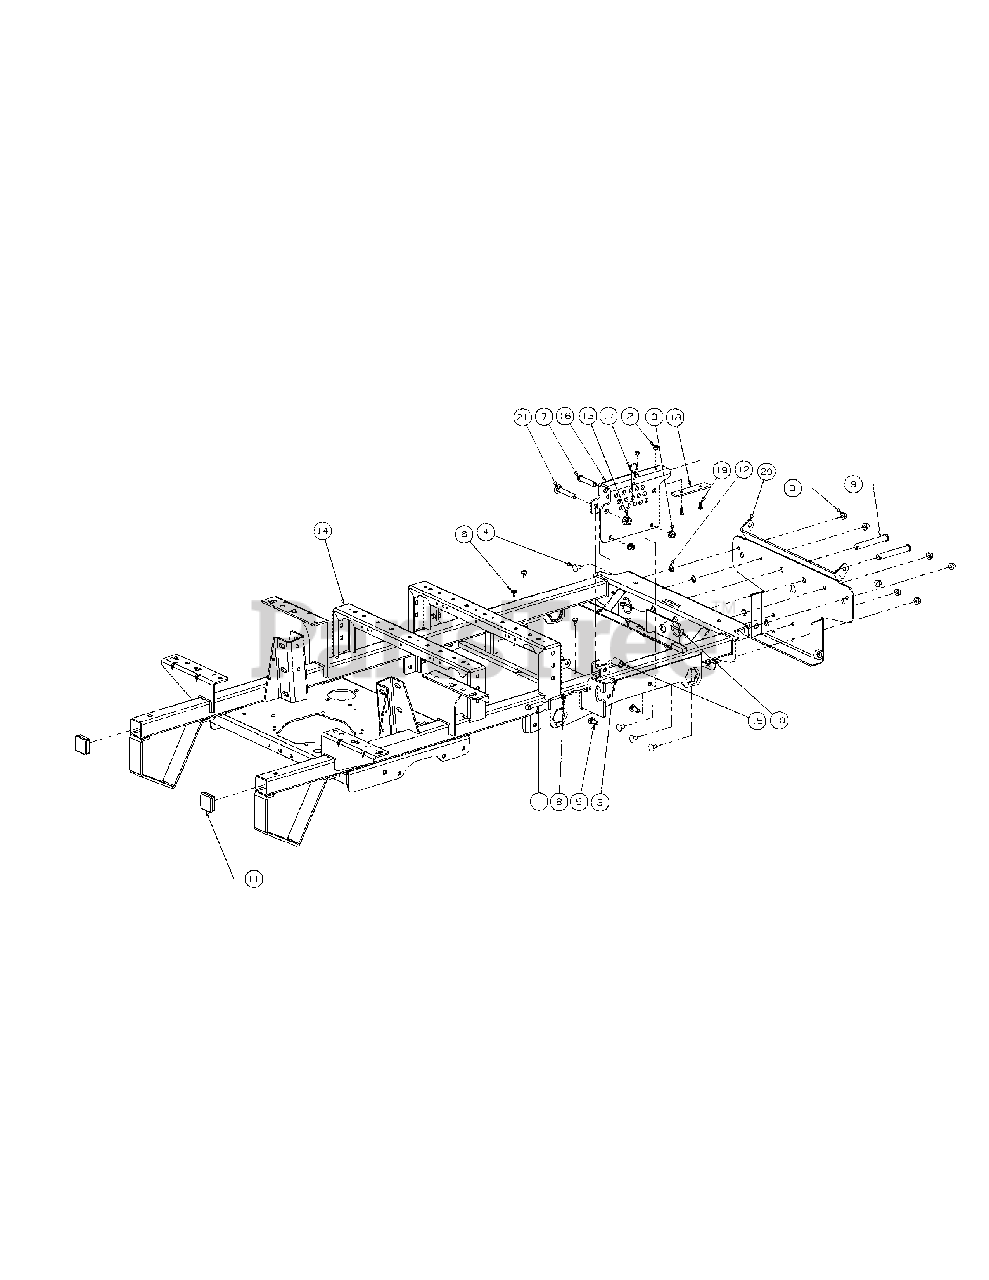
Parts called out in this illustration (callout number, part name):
1	Hex Cap Screw 3/8-16 x 2.00
2	Lock Nut w/Nylon Insert
3	Hex Nut, 3/8-16 Flange Lock
4	Carriage Bolt, 3/8-16 x .75 Long
5	Carriage Bolt, 3/8-16 x 1
6	Rubber Bumper, .62 OD x .22 Thick
7	Clevis Pin, .500 Dia. x 2.50 Lg.
8	Nut, 3/8-16, Jam
9	Clevis Pin, .625 Dia x 4.375 Long
10	Linch Pin, 3/16 Dia.
11	Plug, Square Tube
12	Push Retainer, 3/8
13	Nut, 1/2-13, Flangelock
14	Frame Assembly
15	Spacer, .51 ID x .75 OD x 1.40
16	Lift Index Bracket
17	HitchPin, .120 Dia. x 3.0
18	Wear Plate, 1.25 x 5.00
19	Flat Head Cap Screw, 1/4-20 x .75
20	Bracket Assembly, Frame, Front
21	Carriage Bolt, 1/2-13 x 3.00
